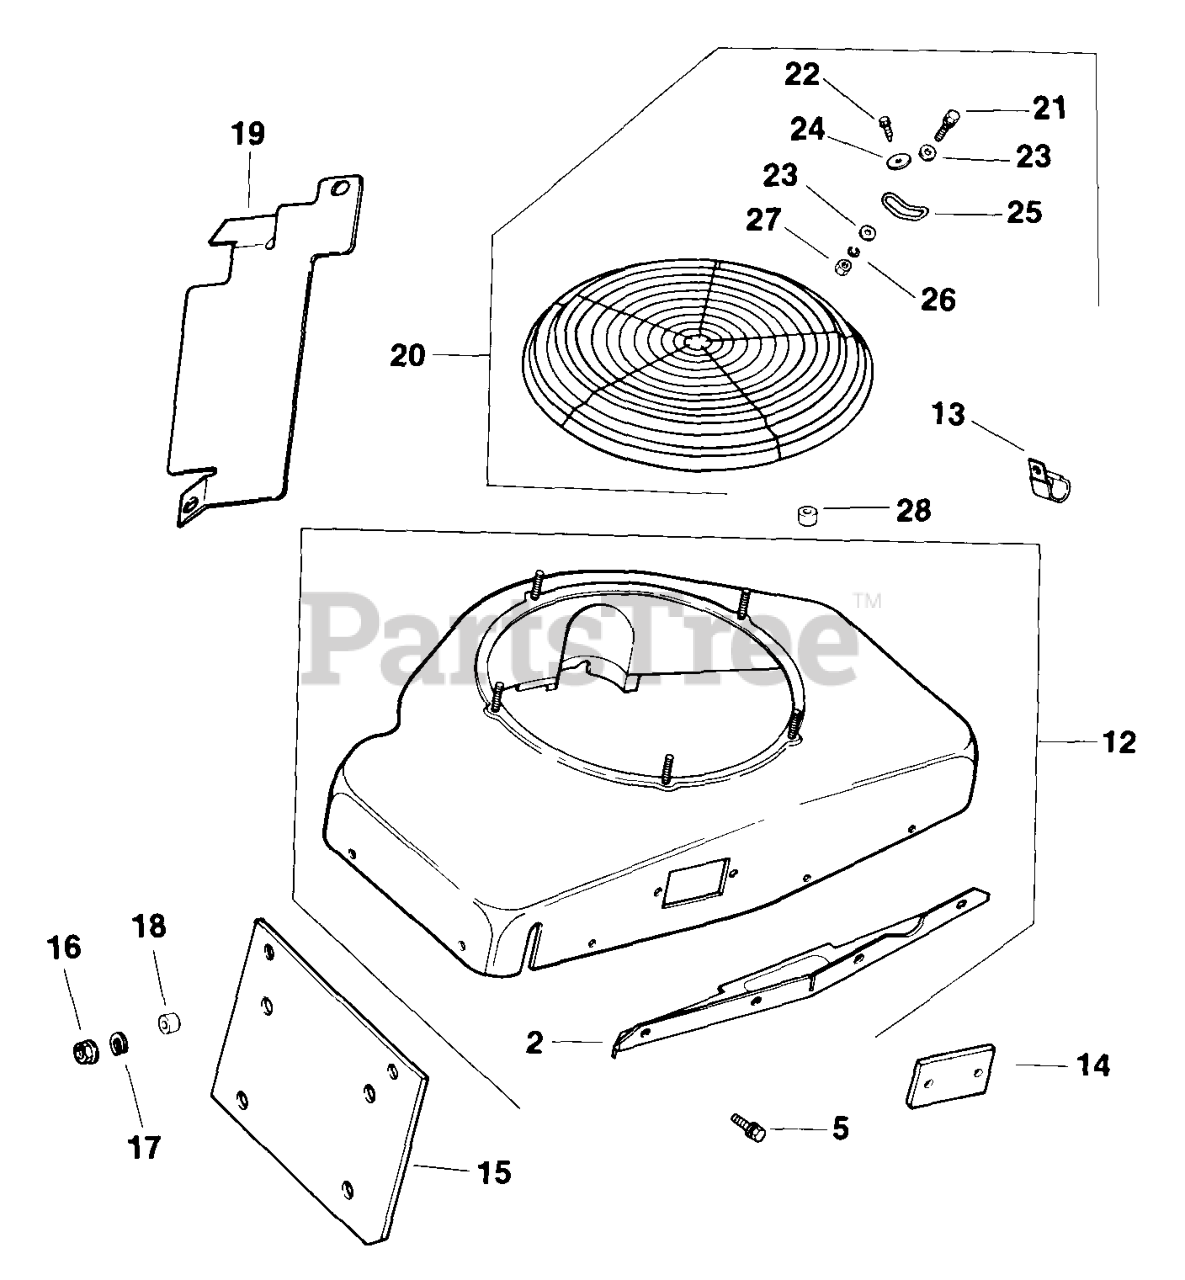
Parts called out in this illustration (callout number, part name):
2	SUPPORT - (#DSC)
5	SCREW, WSH HD TAP 1/4-20X7/16" USE 25 086 106-S
12	KIT, HOUSING
20	KIT, GUARD - (#DSC)
22	SCREW - USE 25 086 40
23	WASHER - USE X-25-92
25	BRACKET - DISCONTINUED
26	WASHER, SPRING LOCK #10
27	NUT, MACH SCREW #10-24 GRD 2 USE 25 100 17-S
